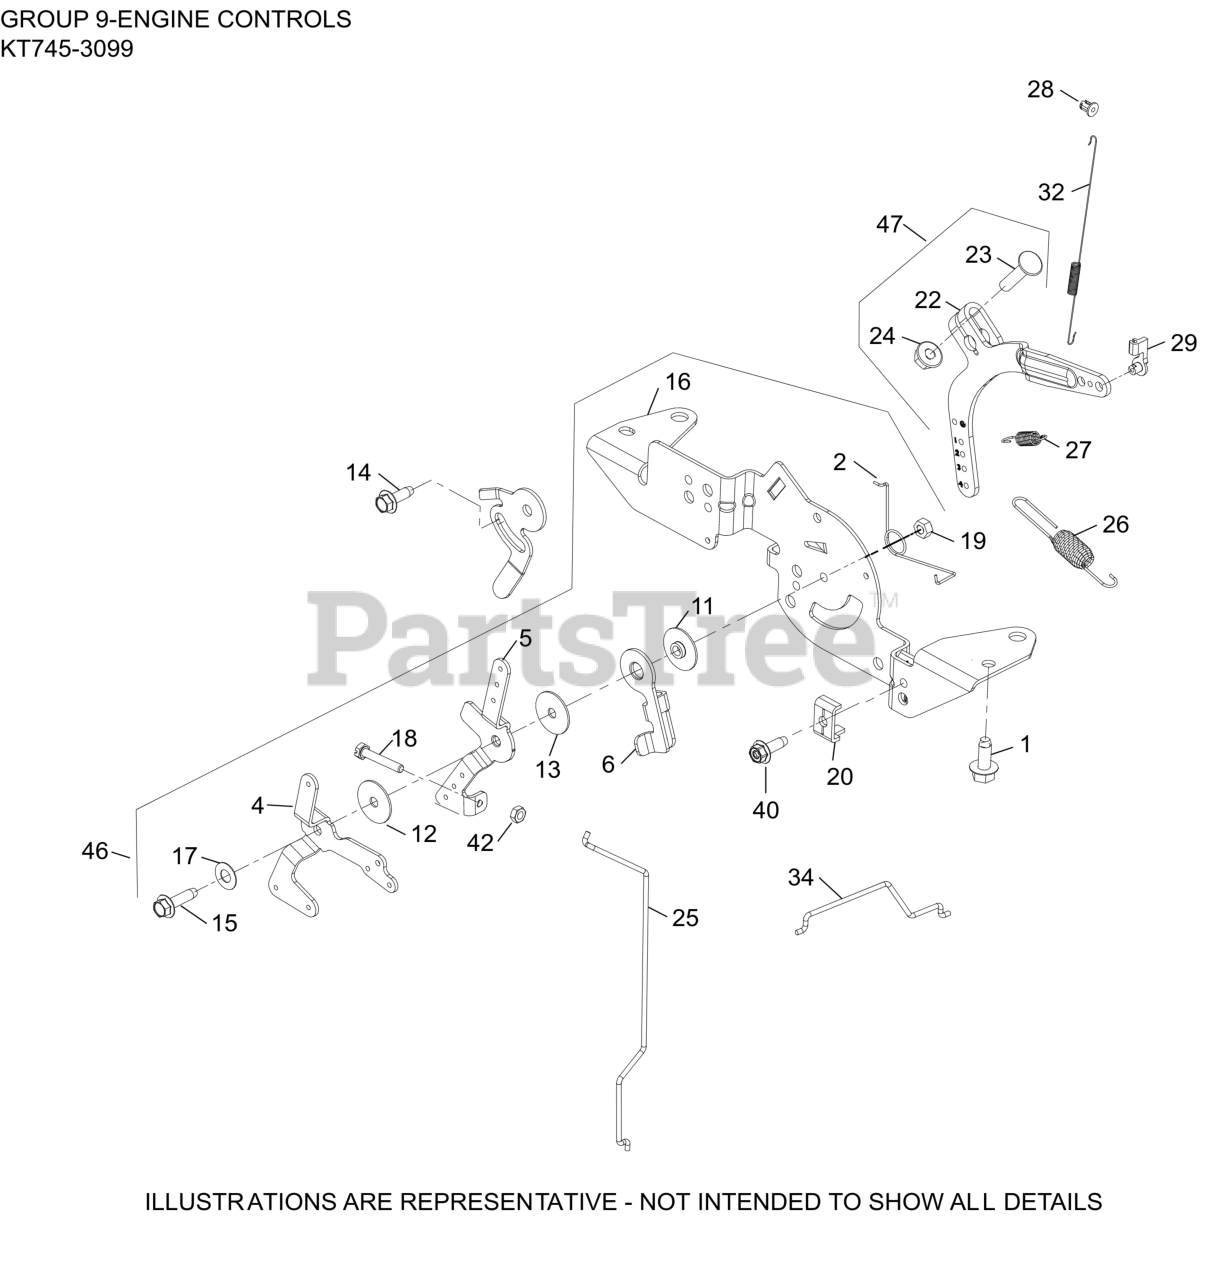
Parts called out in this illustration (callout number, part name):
1	SCREW, THREAD FORMING
2	SPRING, CHOKE RETURN
4	LEVER, CHOKE
5	LEVER, THROTTLE CONTROL
6	LEVER, THROTTLE ACTUATOR
11	SPACER, CONTROL ASSEMBLY
12	WASHER, FLAT 5.5 MM
13	WASHER, FLAT 5 MM
14	SCREW, THREAD FORMING
15	SCREW, THD FRM-USE 25 086 473-S
16	BRACKET, SPEED CONTROL
17	WASHER, SPRING 1/4"
18	SCREW, SLT HD CAP M4X0.7X25
19	NUT, LOCK M5X.8
20	CLAMP, CABLE CABLE
22	LEVER, GOVERNOR - (#2409069S)
23	BOLT, RD HD SQ NECK M6X1.0X25
24	NUT, FLG M6X1.0
25	LINKAGE, CHOKE
26	SPRING, GOVERNOR (ORANGE)
27	SPRING, GOVERNED IDLE
28	BUSHING, LINKAGE RETAINING
29	BUSHING, THROTTLE LINKAGE
32	SPRING, LINKAGE
34	LINKAGE, THROTTLE
40	SCREW, THREAD FORMING
42	NUT, M4X0.7
46	CONTROL ASSEMBLY, DUAL WIRE
47	LEVER, GOVERNOR ASSEMBLY
